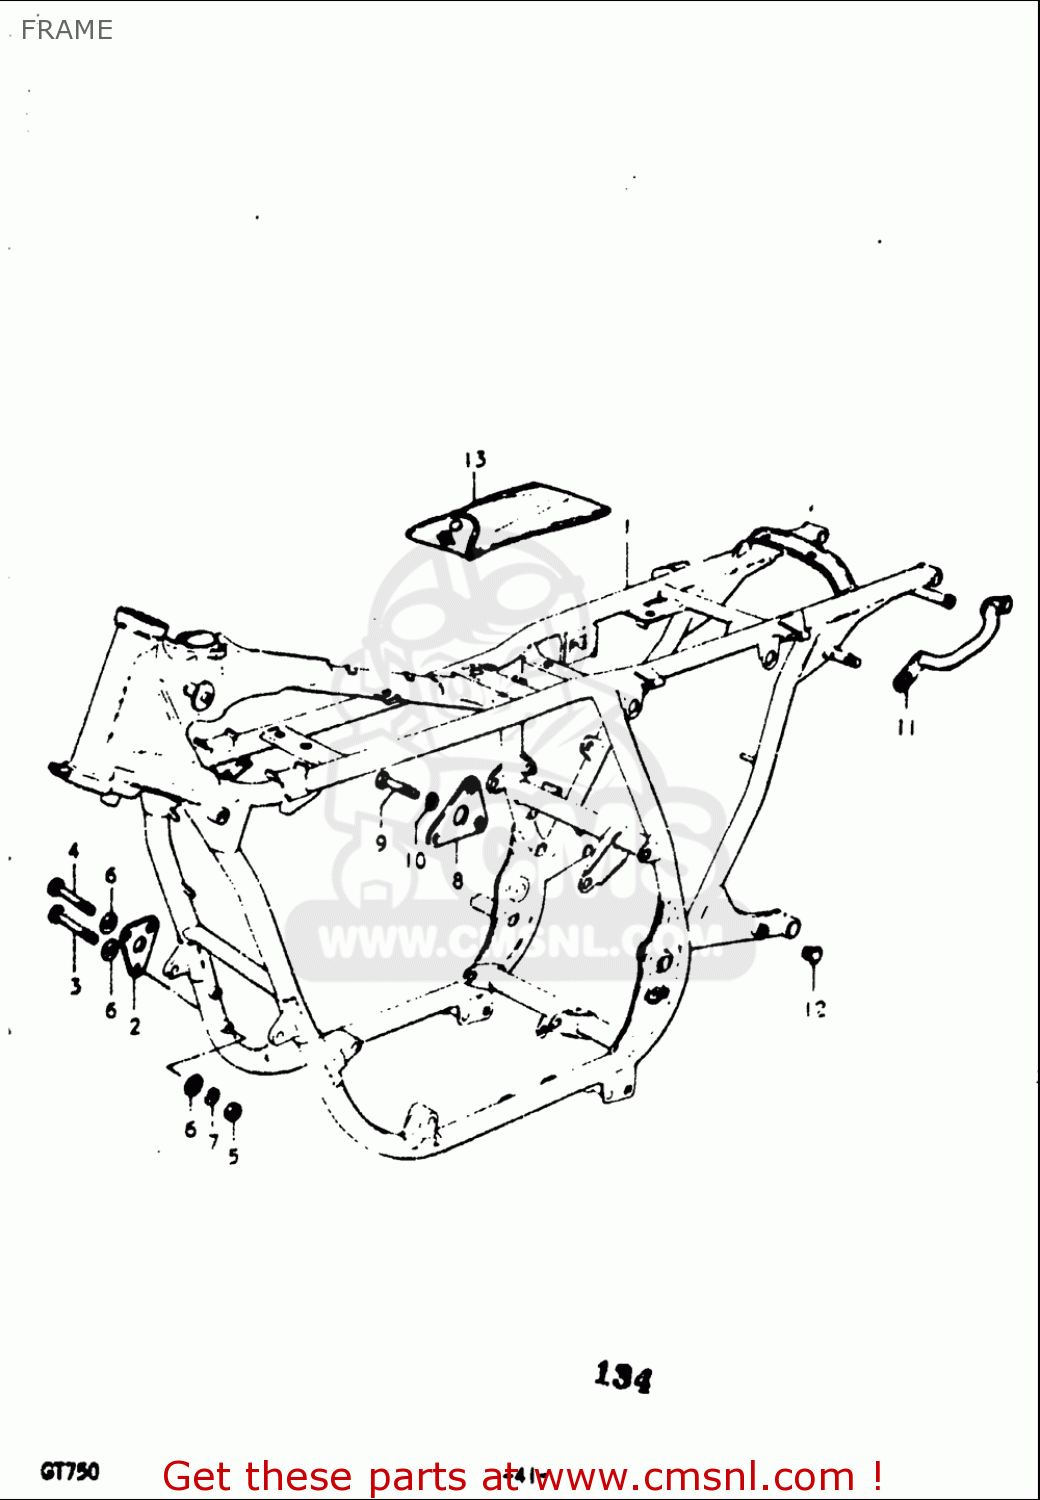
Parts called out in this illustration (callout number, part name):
3	BOLT
4	BOLT
5	NUT
6	WASHER
7	WASHER,LOCK
9	BOLT
10	WASHER,LOCK
12	CAP(OD:14)
13	TOOL ASSY
